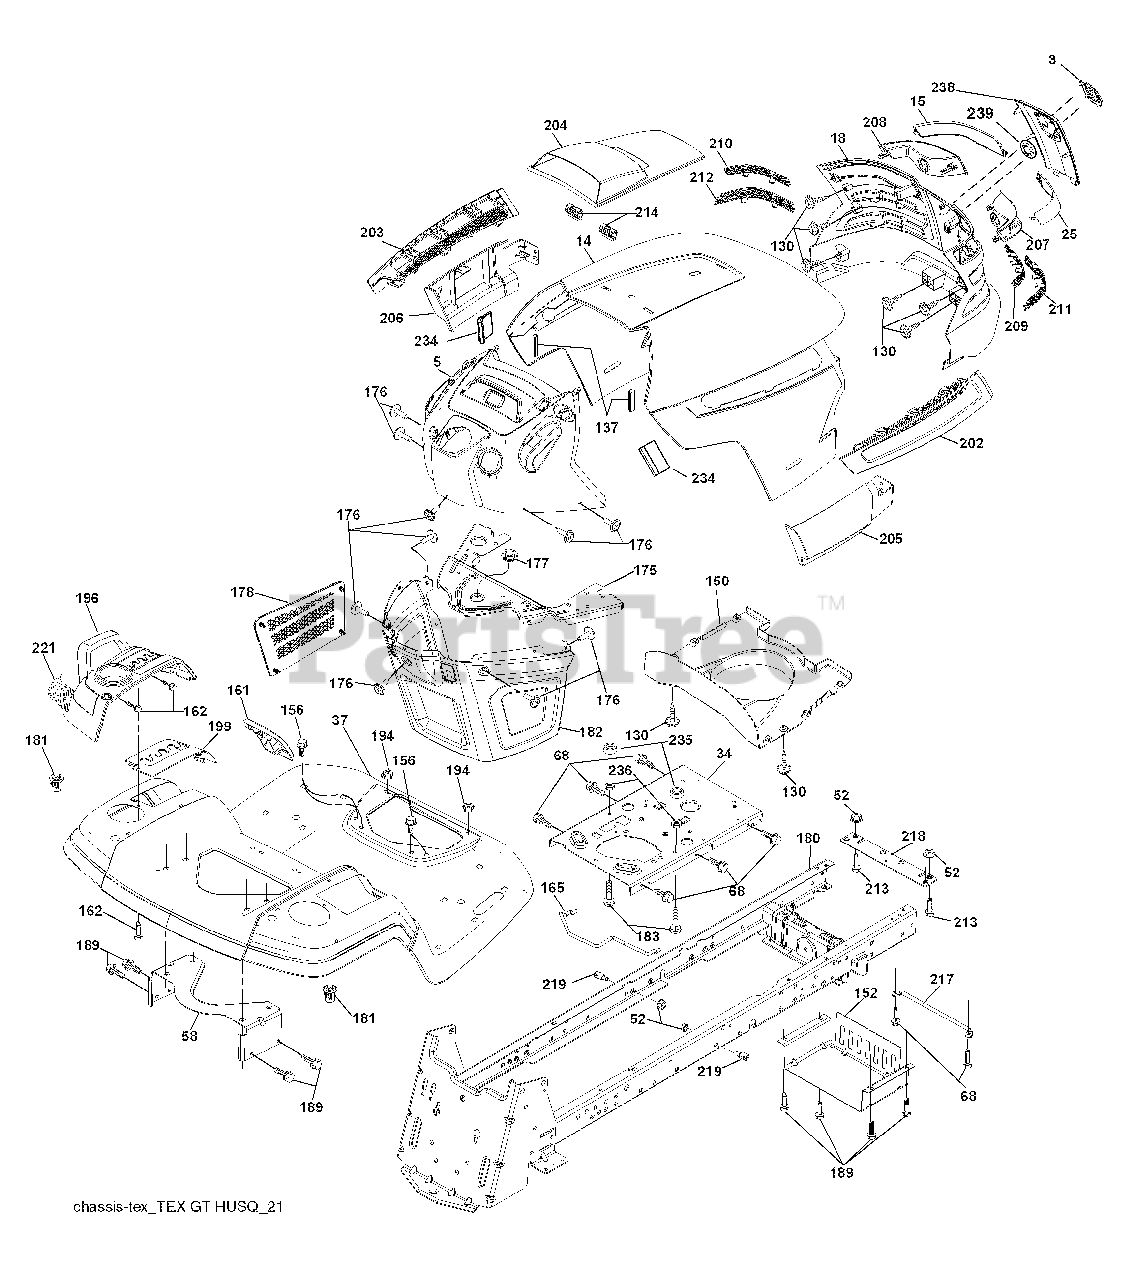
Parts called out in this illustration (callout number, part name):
3	Logo
5	Dash
14	Hood
34	Plate Engine
37	Fender
52	Nut Crown Lock 5/16-18
58	Bracket Fender
68	Screw 5/16-18 x 1/2
130	Screw #10 x .750 BOS Thread
137	Bumper Dash
150	Duct Heat Hood
152	Shield Browning/Debris
156	Screw 5/16-18 x 3/4
161	Console Fuel Window
162	Screw Hex Wsh Hi-Lo 1/4 x 1/2
165	Bracket Support Tank
175	Crossmember
176	Screw 10-24
177	Bushing Steering
178	Cargo Asm. Net
180	Chassis
181	Bushing Mtg. Fender Crgo.
182	Dash Lower
183	Bolt 5/16-18 unc x 1-1/4
189	Screw 5/16-18 x 3/4
194	Nut Lock Hex Flange 5/16-18
196	Console Asm. Deck Lift
199	Plate Deck Lift
202	Vent Side Hood RH
203	Vent Side Hood LH
204	Vent Asm Hood Top
205	Skirt Hood Side RH
206	Skirt Hood Side LH
209	Insert Hex Top RH
210	Insert Hex Top LH
211	Insert Hex Bottom RH
212	Insert Hex Bottom LH
213	Bolt Hex Hd 5/16-18 unc x 3/4
214	Clip Retainer
219	Stud Fastener
221	Reflector LH
234	Bumper Hood
235	Spacer Fender
236	Nut Center Lock 5/16-18 unc
